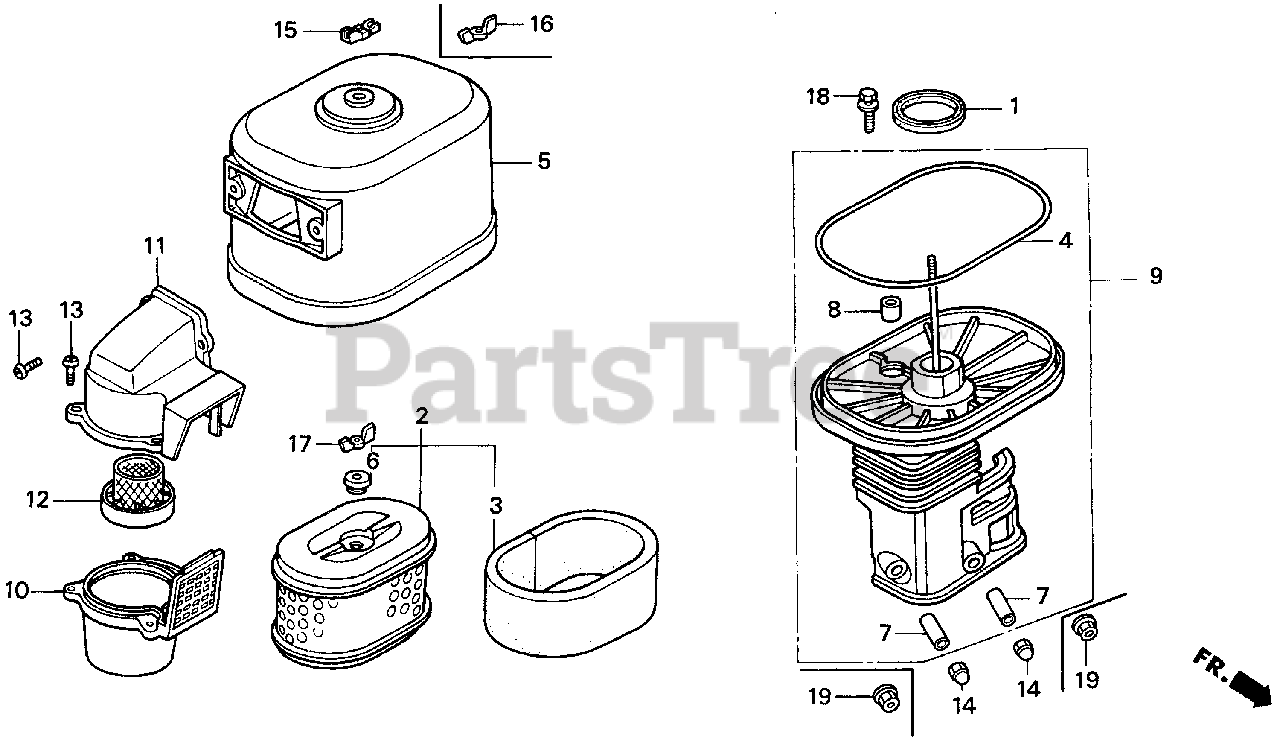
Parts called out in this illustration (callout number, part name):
1	GASKET, ELBOW
2	ELEMENT, AIR CLEANER
3	FILTER (OUTER)
4	SEAL, AIR CLEANER COVER
5	COVER, AIR CLEANER (CYCLONE)
6	GROMMET, AIR CLEANER
7	COLLAR, AIR CLEANER
8	COLLAR B, AIR CLEANER
9	ELBOW, AIR CLEANER
10	CASE, PRE AIR CLEANER
11	CAP, PRE AIR CLEANER
12	GUIDE, PRE AIR CLEANER
13	SCREW, PAN (5X16.5)
14	NUT, CAP (6MM)
15	WINGNUT, AIR CLEANER COVER
15	WINGNUT (6MM)
16	WINGNUT, TOOL BOX SETTING
17	WINGNUT, TOOL BOX SETTING
18	BOLT-WASHER (6X22)
19	NUT, FLANGE (6MM)
